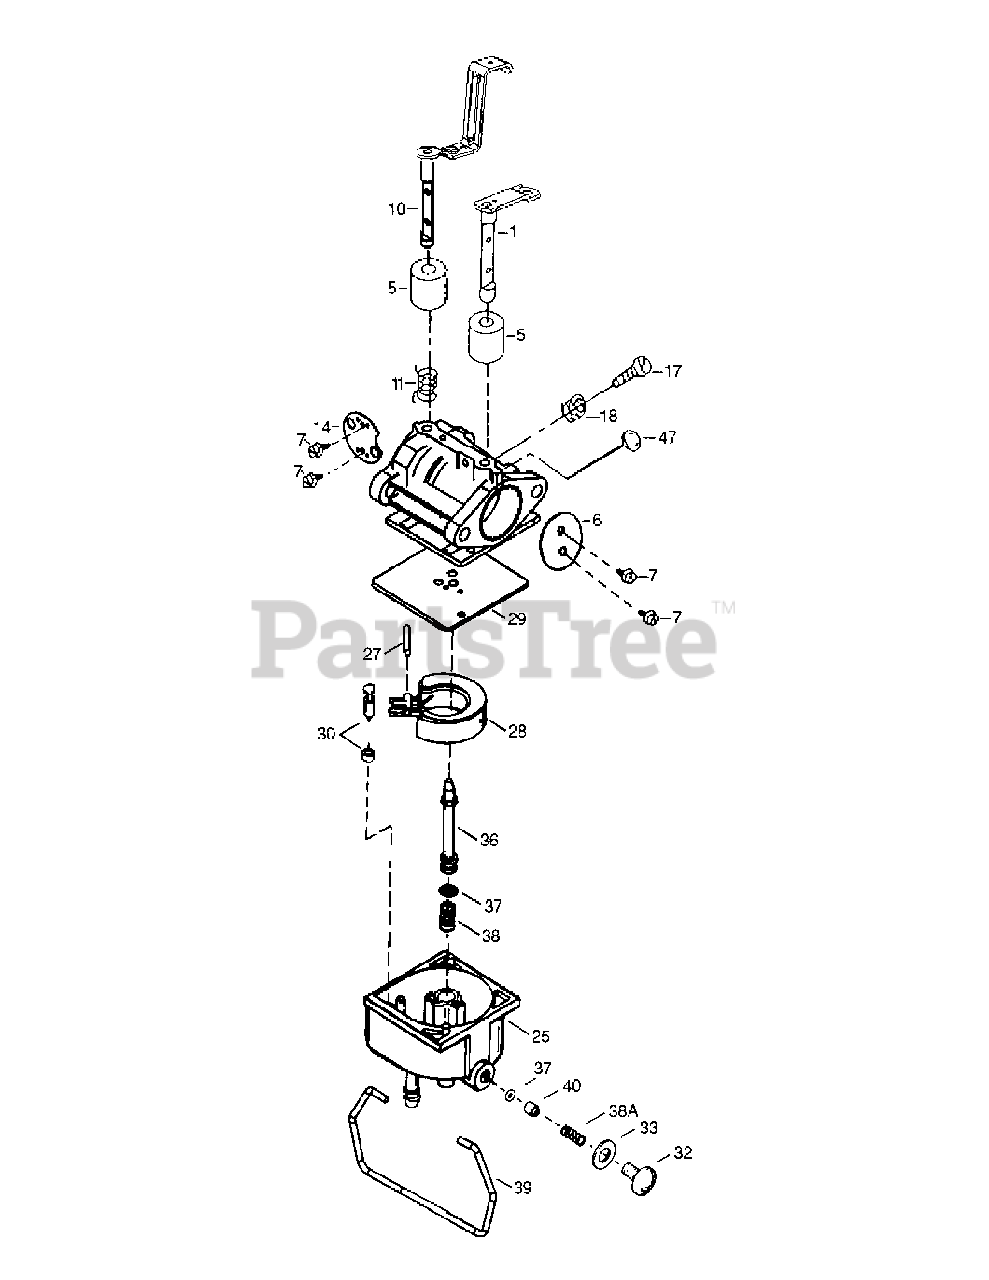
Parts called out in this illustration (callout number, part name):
1	Throttle Shaft & Lever Assembly
6	Throttle Shutter
7	Throttle & Choke Shutter Screws
10	Choke Shaft & Lever Assembly
11	Choke Return Spring
14	Choke Shutter
17	Throttle Crack Screw/Idle Speed Screw
18	Tension Spring
25	Float Bowl Assembly
25A	Float Bowl Repair Kit
29	Float Bowl to Body Gasket
30	Inlet Needle & Seat
32	Bowl Drain Screw
33	Bowl Drain Washer
36	Main Nozzle Tube
37	O-Ring
38	Spring, Main Nozzle Tube
39	Float Bowl Retainer
40	Main Fuel Jet
47	Welch Plug, Idle Mixing Well
